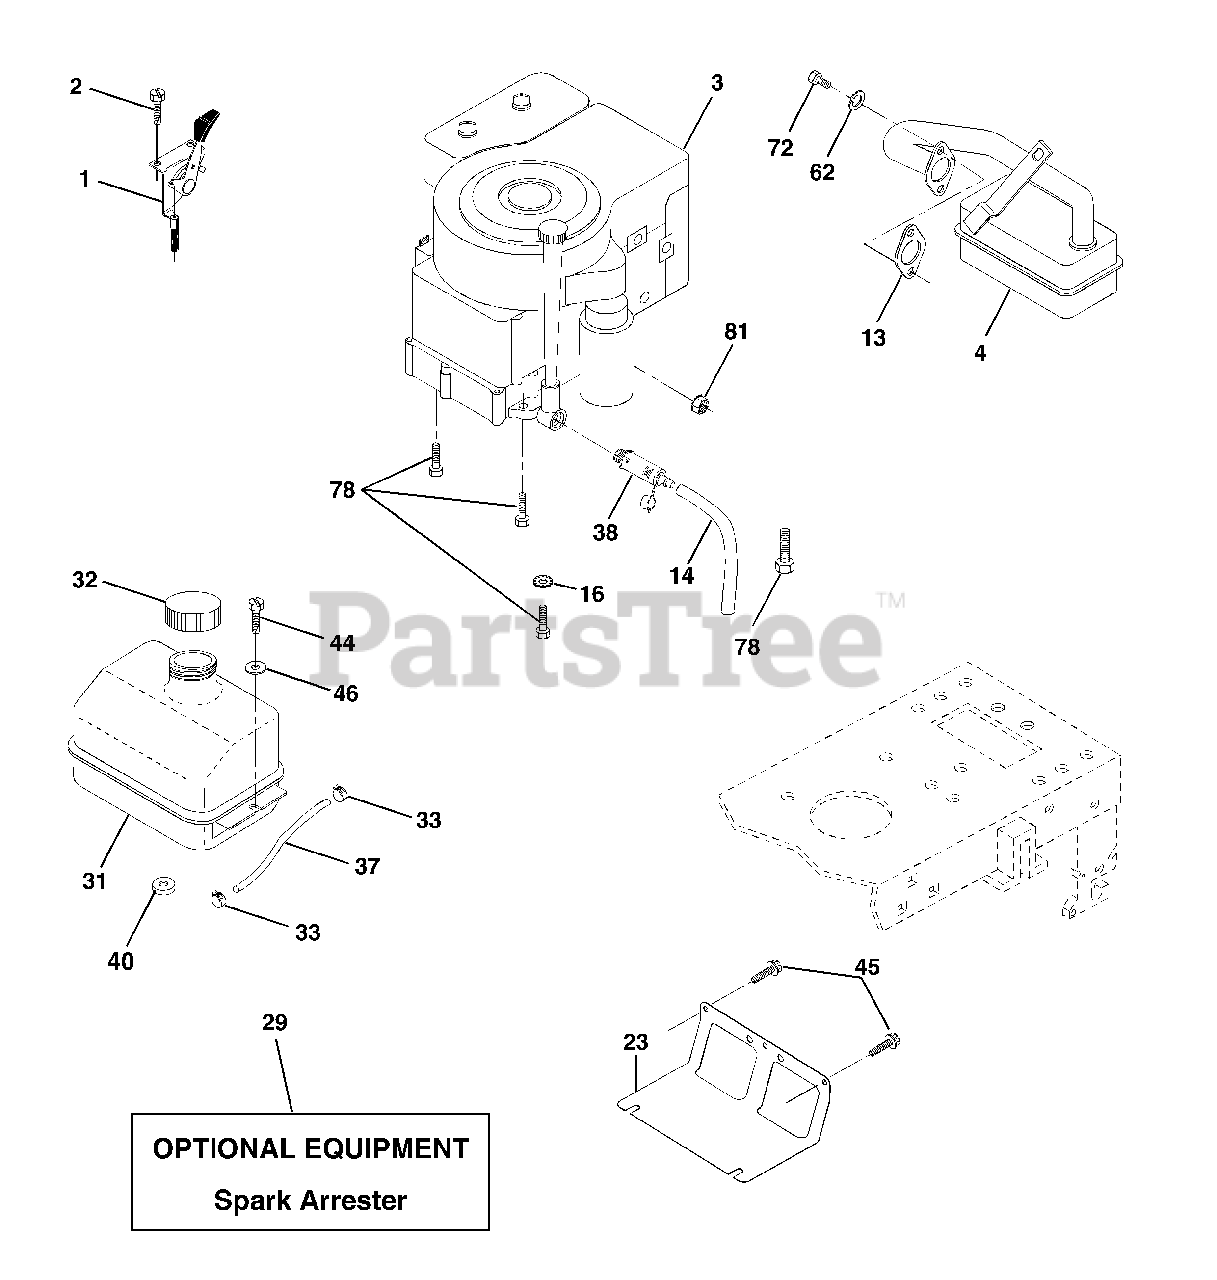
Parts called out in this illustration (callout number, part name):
1	Control Th/ch Flag
2	Screw Hex Thd Cut 1/4-20x5/8 T
4	Muffler Exhaust B&S Lc
13	Gasket Eng 1 313 Id Tin Plated
14	Tube Drain Oil Easy
16	Washer Lock Ext Tooth 3/8
23	Shield BRN/DBR Guard
29	Kit Spark Arrestor (Flat Scrn)
31	Tank Fuel Front
32	Cap Asm Fuel
33	Clamp Hose
37	Line Fuel 20"
38	Plug Drain Oil Easy
40	Bushing Snap Nyl Blk Fuel Line
44	Screw Thdrol 1/4-20 x 3/4
45	Screw Hex Wsh Thdrol 3/8-16
46	Washer 9/32 X 7/8 X 16 Ga
62	Washer Lock Hvy Hlcl Spr
72	Screw Hexcap 5/16-18 x 3/4
78	Screw 3/8-16 x 1-1/4
81	Nut Keps Hex 1/4-20 Unc
